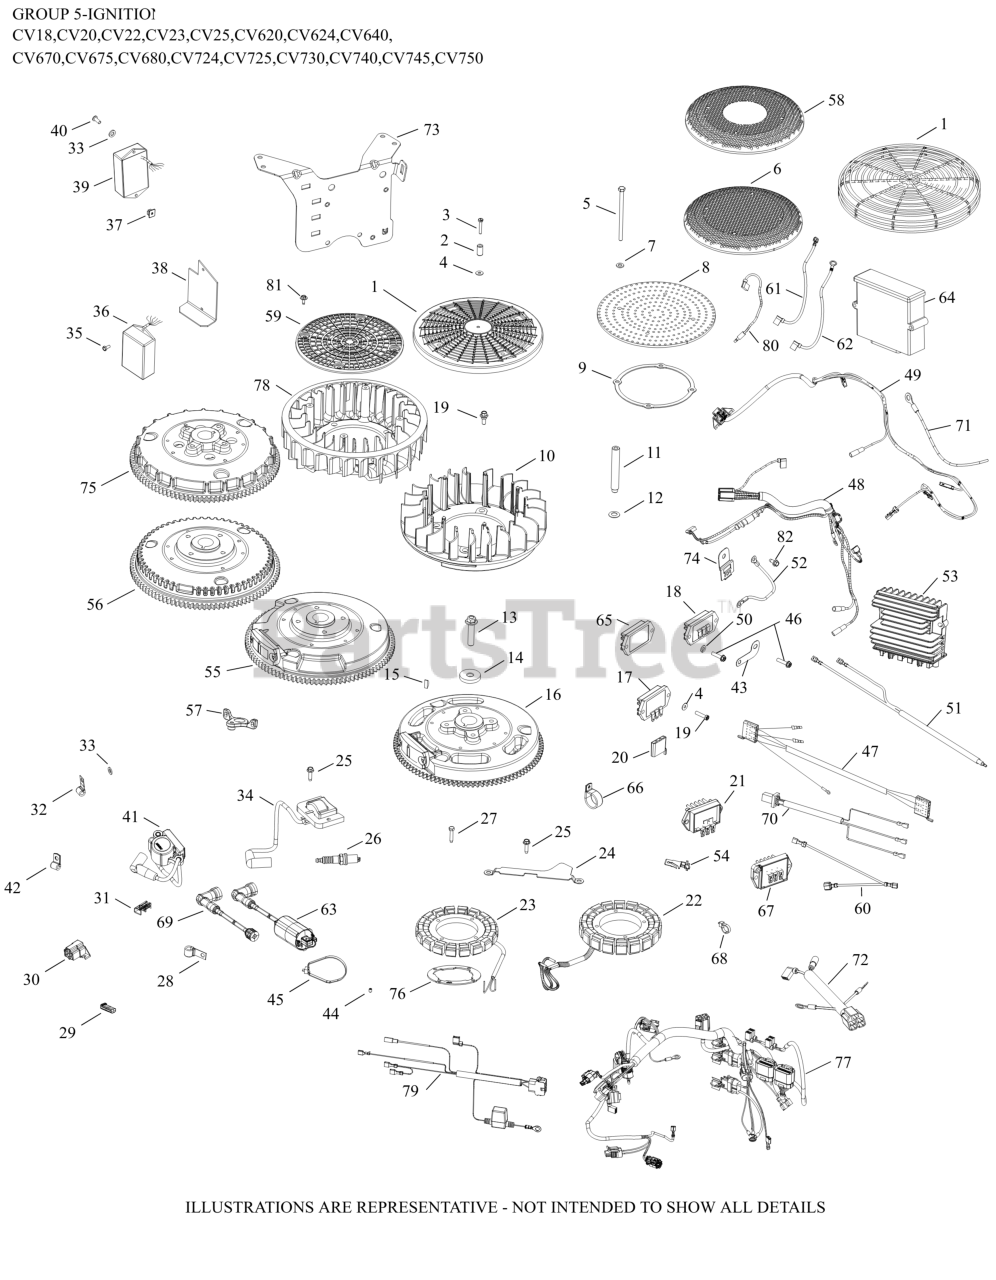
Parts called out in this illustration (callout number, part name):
5	SCREW, CAP M6X1.0X99.5
6	SCREEN, GRASS
7	WASHER, FLAT 1/4" (O.D. 5/8")
9	RING, SUPPORT
12	WASHER, SPRING 10 MM
13	SCREW, FLG M10X1.5X45-USE 25 086 361-S
14	WASHER, FLAT 13/32"
15	KEY, 3/16" X 5/8"
18	REGULATOR/RECT 12/15A HALF-WAVE STD
20	CONNECTOR
23	KIT, 15 / 20 AMP STATOR
25	SCREW, THREAD FORMING
26	SPARK PLUG, RFI
27	SCREW, THREAD FORMING
28	CLIP, CABLE
33	WASHER, FLAT 1/4" (O.D. 1/2")
34	MODULE, EMC/RFI COMPLIANT
44	SCREW, SKT SET #10-24X1/4"
46	SCREW, HEX FLANGE HI-LO
48	HARNESS, WIRING
50	WASHER, LOCK
71	TUBE,RFI FLEXIBLE SLEEVE(219mm)
